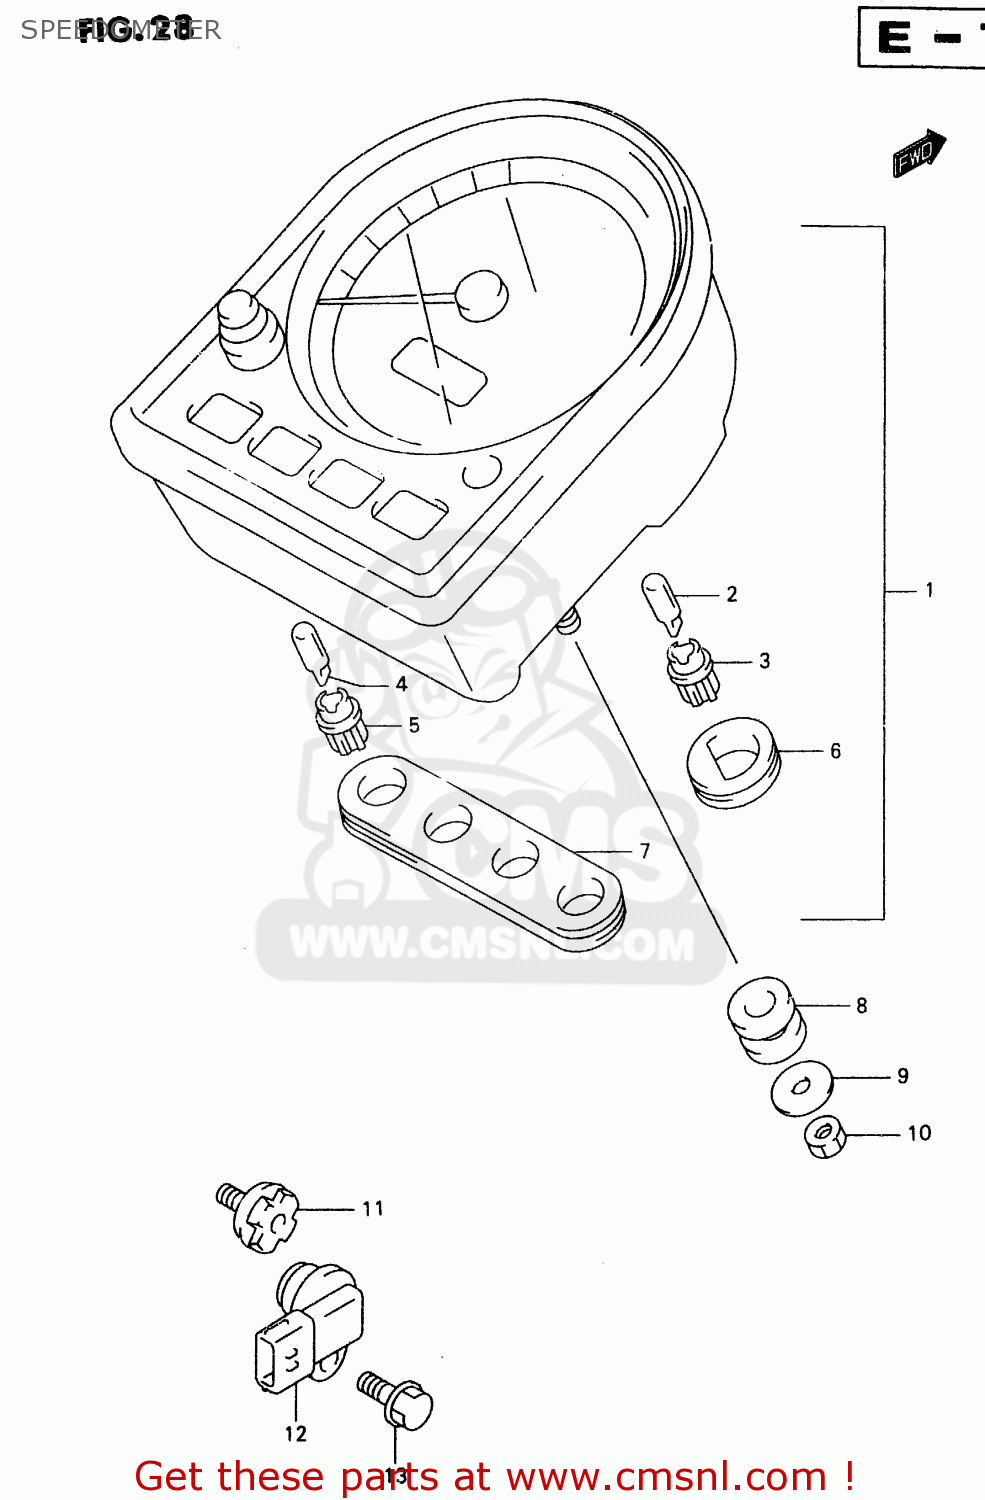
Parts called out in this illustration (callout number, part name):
1	SPEEDOMETER (KILO)
2	BULB(14V,0.84W)
3	SOCKET,BULB
4	BULB(12V1.7W,WB372,T7)
5	SOCKET
6	BLIND,CAP
7	BLIND,CAP
8	CUSHION,METER
9	WASHER(5.5X16X1.2)
10	NUT
11	ROTOR,SPEED
12	SENSOR,SPEED
13	BOLT(6X16)
